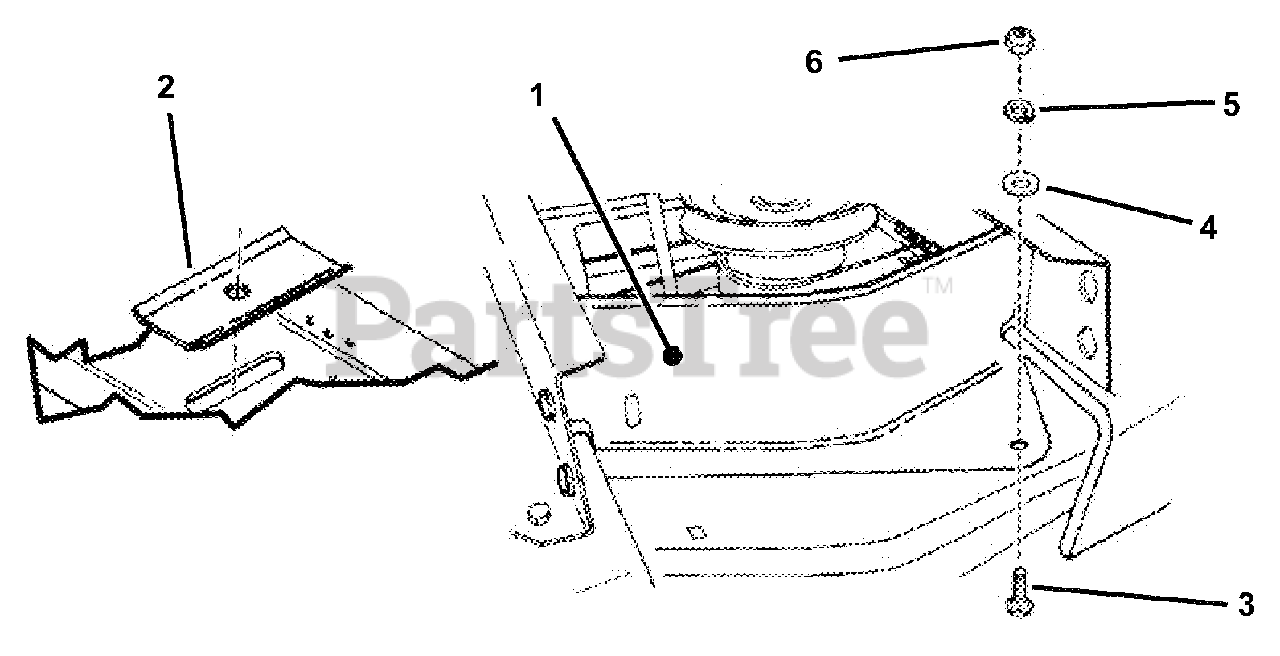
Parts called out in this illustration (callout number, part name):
1	BAFFLE, Deck (42113S Rider)
2	PLATE, Idler (Adjusting Slot)
3	BOLT, 3/8-16 x 3/4" Square Neck Carriage
4	WASHER, 3/8" SAE Flat
5	WASHER, 3/8" Split Lock
6	NUT, 3/8-16 Hex
